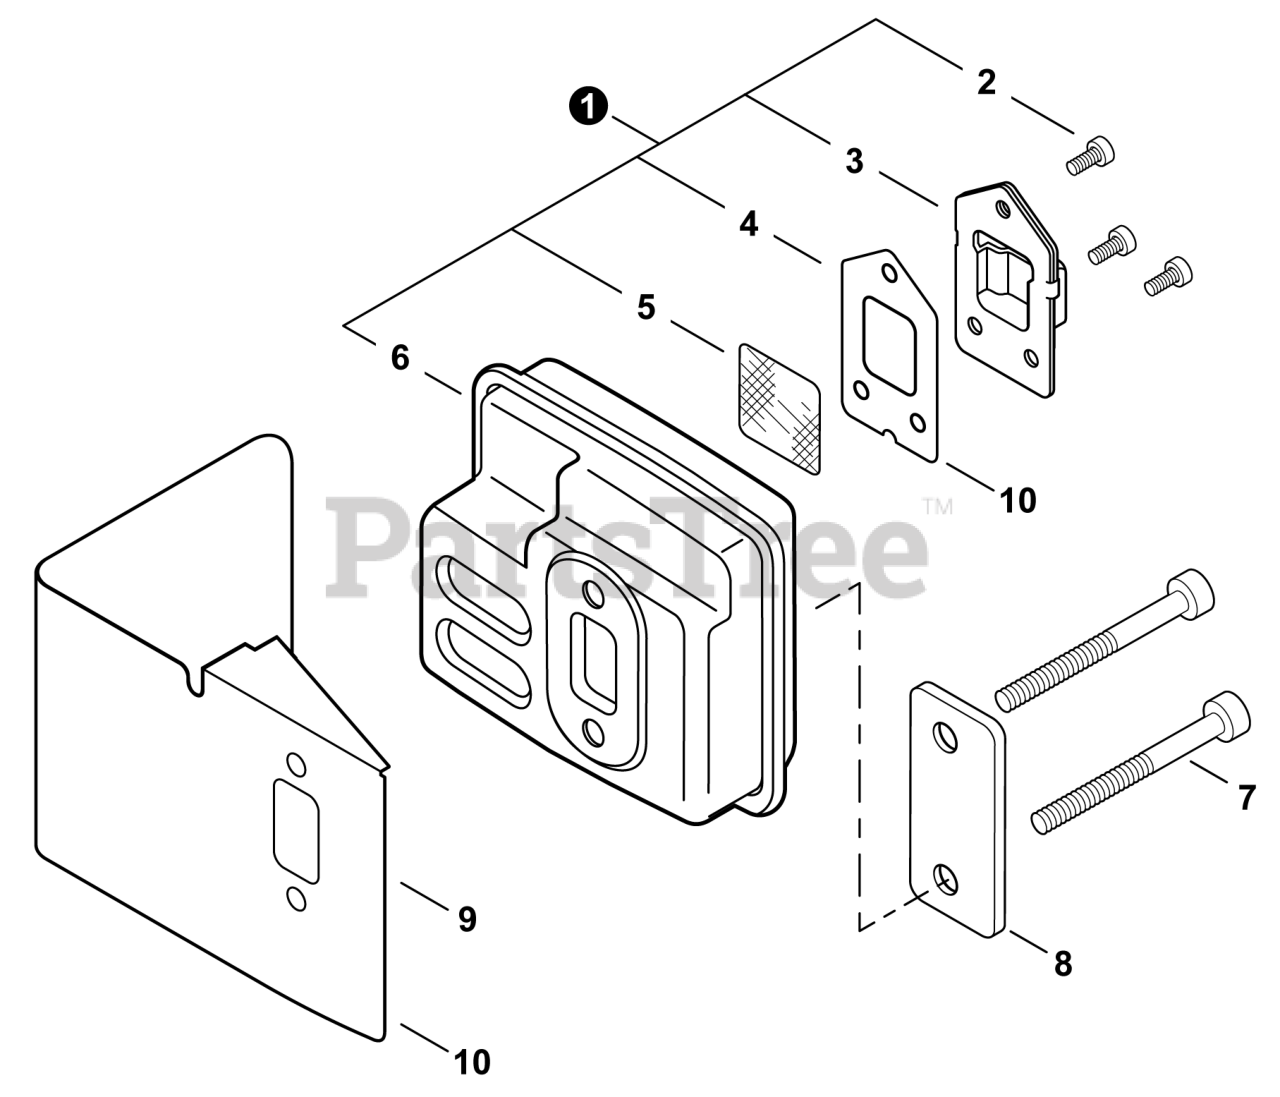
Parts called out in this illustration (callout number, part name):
1	MUFFLER ASSY
2	BOLT, TORX 4×8
3	GUIDE, EXHAUST
4	GASKET, EXHAUST
5	SCREEN, SPARK ARRESTER
7	BOLT, TORX 5×55
8	PLATE, EYE
9	HEAT SHIELD, EXHAUST
10	GASKET KIT: ENGINE, INTAKE, EXHAUST
